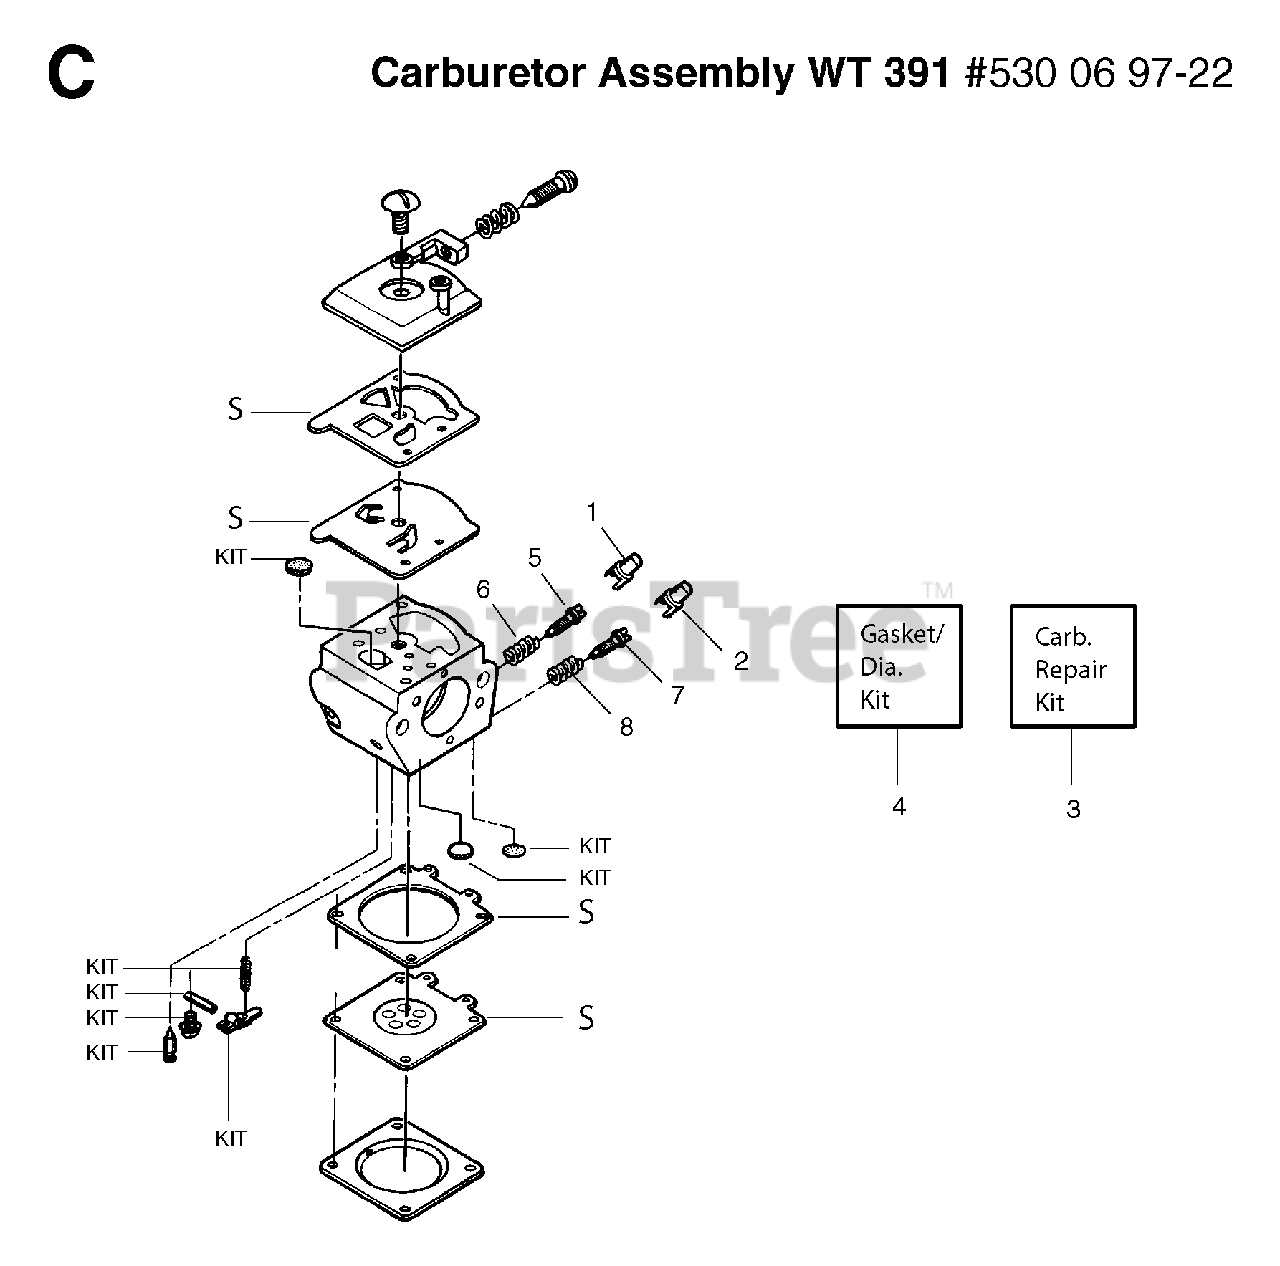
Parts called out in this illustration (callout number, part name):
2	LIMITER CAP (LOW-BLUE)
3	CARB REPAIR KIT
4	GASKET/DIAPHRAGM KIT
5	LOW SPEED NEEDLE
6	NEEDLE SPRING
7	NEEDLE HIGH SPEED
8	NEEDLE SPRING
